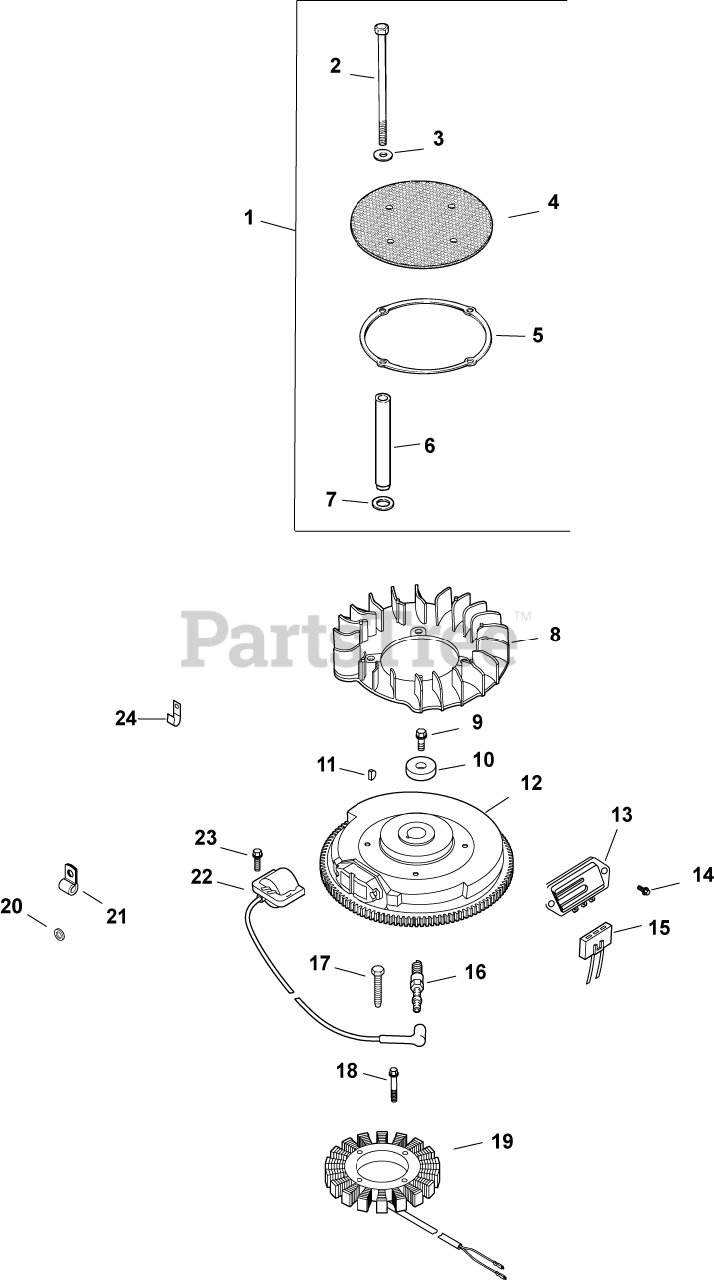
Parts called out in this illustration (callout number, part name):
1	KIT, CHOPPER SCREEN
2	SCREW, CAP M6X1.0X99.5
3	WASHER, FLAT 1/4" (O.D. 5/8")
4	SCREEN, GRASS
5	RING, SUPPORT USE 25 141 08-S
7	WASHER, SPRING 10 MM
9	SCREW, FLG M10X1.5X45 - (#25086361S)
10	WASHER, FLAT 13/32"
11	KEY, 3/16" X 5/8"
12	FLYWHEEL, PAINTED-USE 24 025 59-S
13	REG/RECT-15 AMP (KM)-USE 41 403 10-S
14	SCREW, PHL HD #11-16X7/8"
15	CONNECTOR, BODY (KM)-USE 25 155 41-S
16	PLUG, SPARK (STD)
17	SCREW, M5X0.8X25 - (#25086402S)
18	SCREW, SKT SET #10-24X1/4"
19	KIT, 15 / 20 AMP STATOR
20	WASHER, FLAT 1/4" (O.D. 1/2")
21	CLIP, TUBE & WIRING (KM)
22	KIT, MODULE IGNTN (CDI FIXED)
23	SCREW, FLG THD FRM M5X.8X20-(#25086399S)
24	CLIP, CABLE
